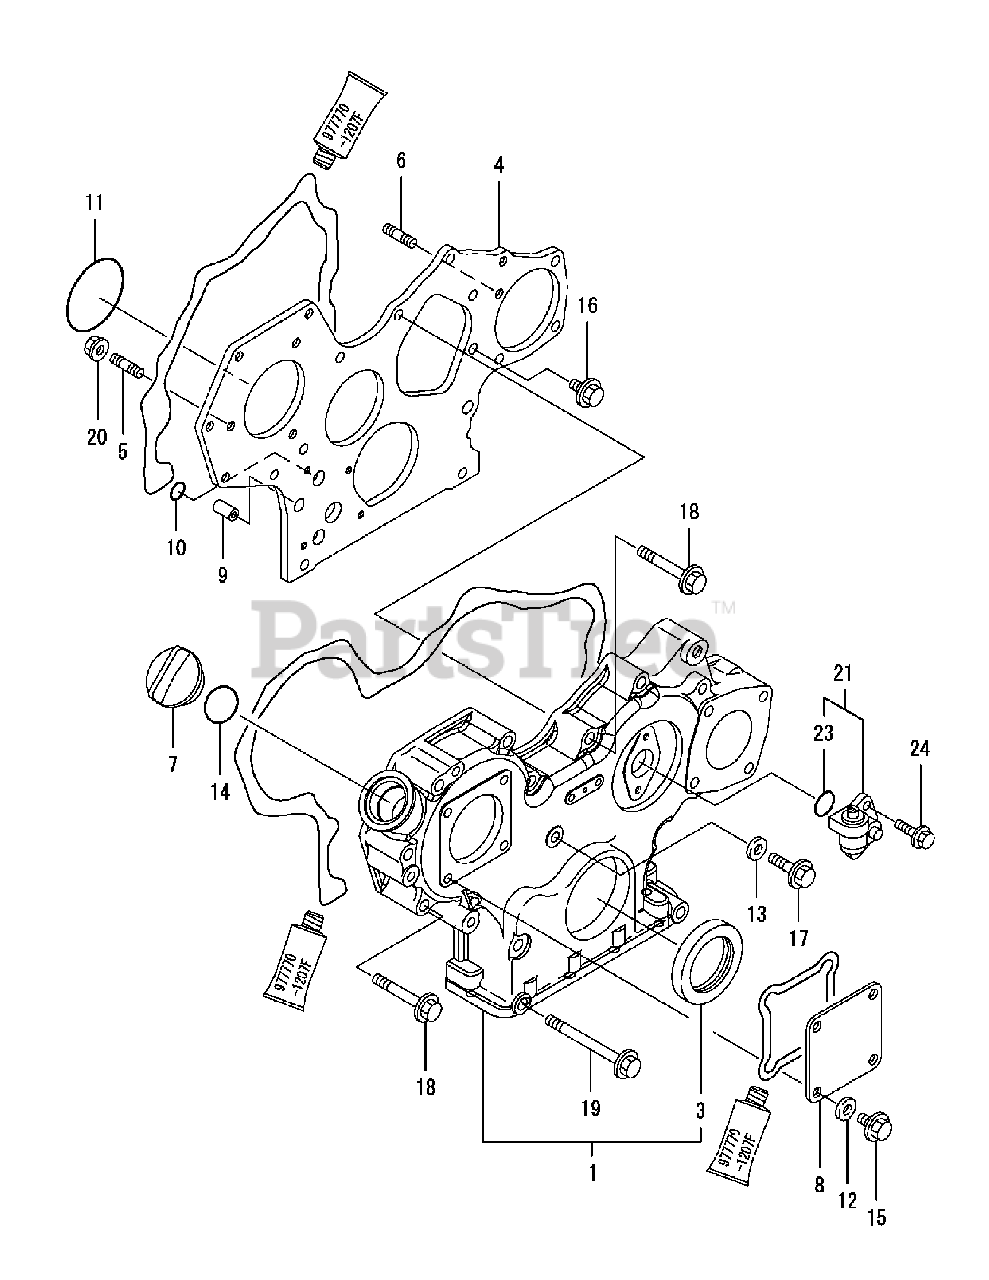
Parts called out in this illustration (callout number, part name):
1	HOUSING ASSY, GEAR
4	FLANGE, GEAR CASE
11	O-RING, F.I.PUMP
12	SEAL WASHER 8S
13	SEAL WASHER 8S
14	O-RING 1A P-32.0
15	BOLT M 8X 16 PLATED
16	BOLT M 8X 16 PLATED
17	BOLT M 8X 30 PLATED
18	BOLT M 8X 55 PLATED
19	BOLT M 8X 85 PLATED
23	O-RING 1A S-24.0
24	BOLT M 6X 16 PLATED
